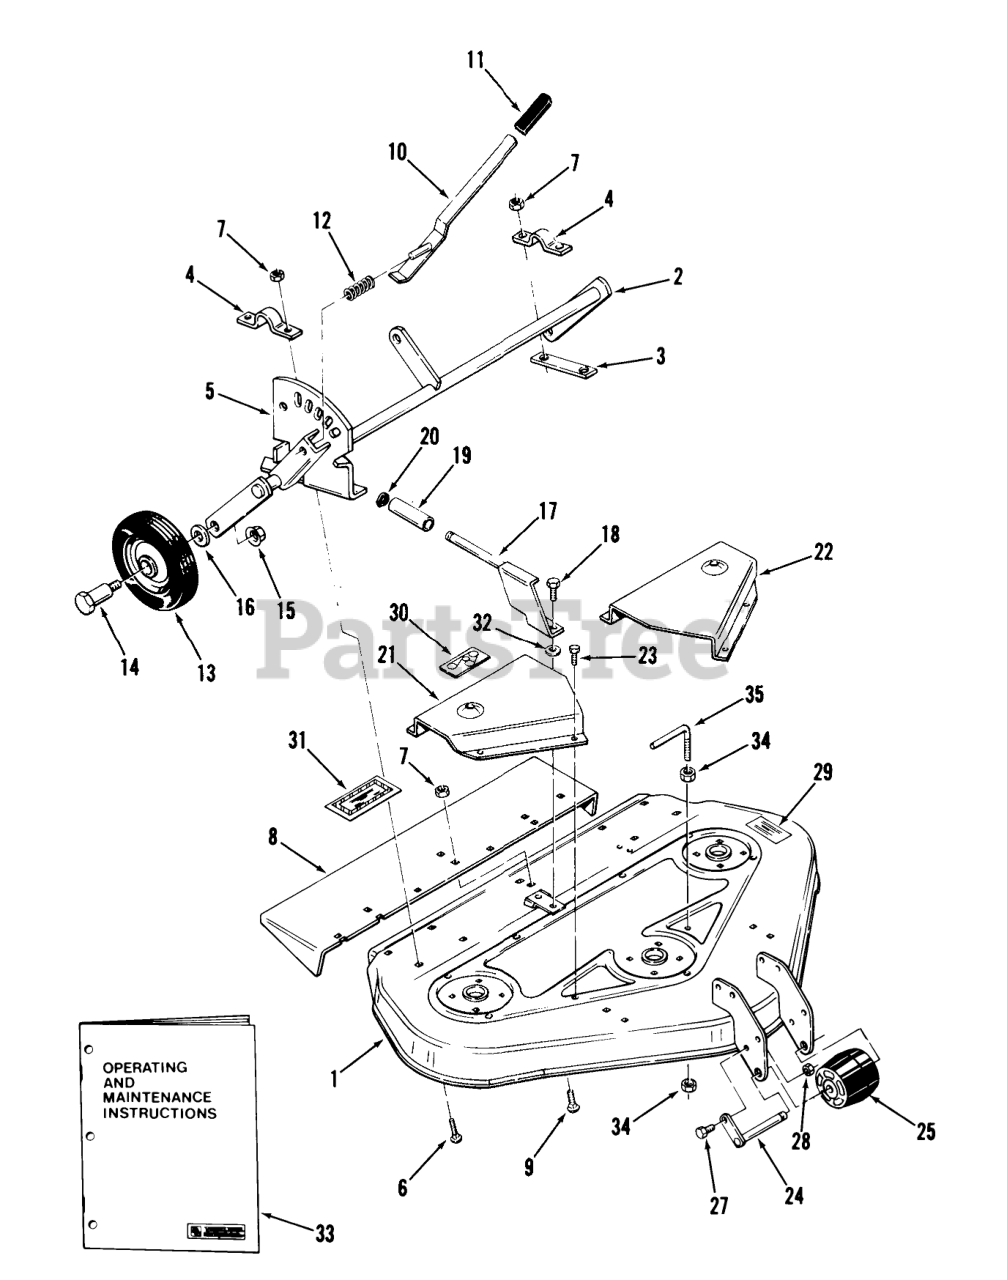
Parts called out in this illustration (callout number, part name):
1	ASSY-MOWER DECK 3 R
2	ASSY GAGE WHEEL S R
3	Strap
4	CLAMP
5	Quadrant
6	Bolt
7	Nut
8	Chute Extension
9	Bolt-Carriage
10	Lever
11	GRIP
12	SPRING-COMPRESSION
13	WHEEL-GAUGE
14	BOLT
15	Nut
16	WASHER
17	Rear Guide
18	Bolt
19	SPACER
20	Snap Ring
21	Belt Cover RH
22	Cover-Belt
23	Bolt #12-14 x 1/2 Self Tapping
24	Roller Shaft
25	Roller
27	H H C S
28	Nut
29	Caution Decal
30	Decal-Height & Belt Adjustment
31	Decal-Caution
32	WASHER
33	Operating and Maintenance Instructions
34	Nut
35	BELT GUIDE
